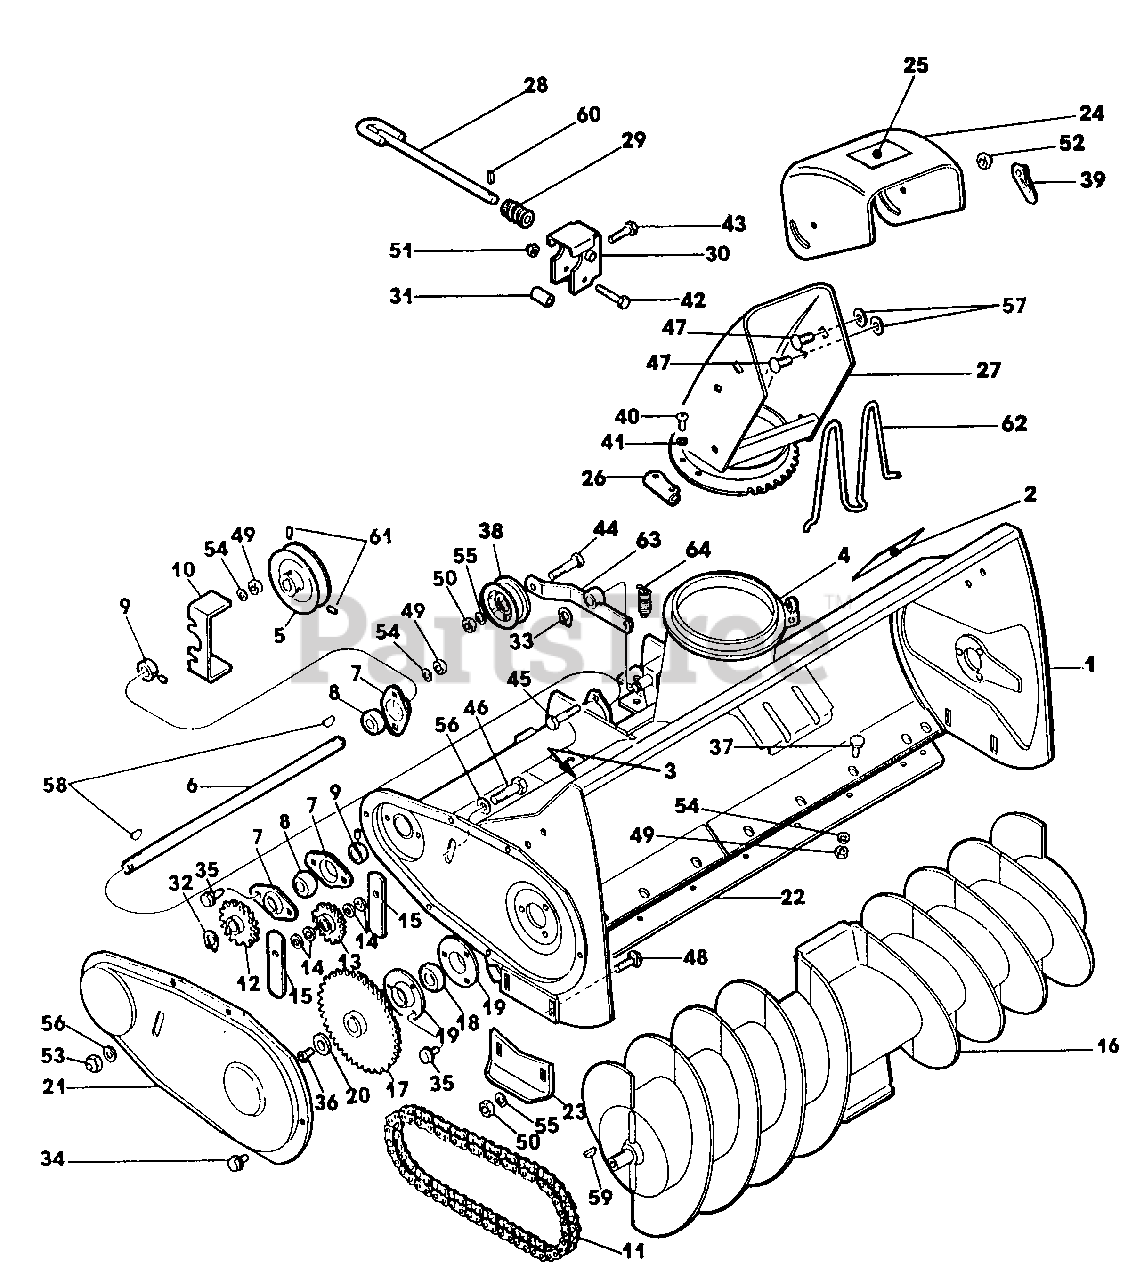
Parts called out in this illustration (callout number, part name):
1	Collector Housing Ass'y. w/Decals
2	Decal-Warning
3	Decal-Danger
4	Chute Collar
5	Pulley
6	Output Shaft
7	Flangette Stamping
8	Bearing
9	Collar w/Setscrew
10	Belt Retainer
11	Roller Chain
12	Sprocket-Drive
13	Idler Sprocket
14	Spacer
15	Strip
16	Auger Assembly
17	Sprocket-Auger
18	Bearing
19	Flangette
20	Washer
21	Drive Cover
22	Scaper Blade
23	Skid
24	Deflector & Decal Assembly
25	Decal-Danger
26	Retainer
27	Discharge Chute And Gear
28	Worm Shaft
29	Worm Gear
30	Worm Support
31	Spacer-Worm Support
32	Snap Ring
33	Snap Ring
34	Lock Screw
35	Lock Screw
36	Machine Screw, Hex Socket Flat Hd
37	Wafer Hd. Bolt
38	Idler Pulley
39	Wing Nut
40	Thread Forming Screw
41	Lock Washer #6
42	Cap Screw, Hex Hd
43	Cap Screw, Hex Hd
44	Cap Screw, Hex Hd
45	Cap Screw, Hex Hd
46	Cap Screw, Hex Hd
47	Bolt, Carriage
48	Bolt, Carriage
49	Nut, Hex
50	Nut, Hex
51	Nut, Hex Cone Lock
52	Nut, Hex Cone Lock
53	Nut, Hex Cone Lock
54	Washer, Spring Lock
55	Washer, Spring Lock
56	Washer, Flat
57	Washer, Flat
58	Key, Woodruff
59	Key, Woodruff
60	Roll Pin
61	Set Screw, Hex Socket Hd. Cup Pt
62	Discharge Guard
63	Idler Arm
64	Spring-Idler
